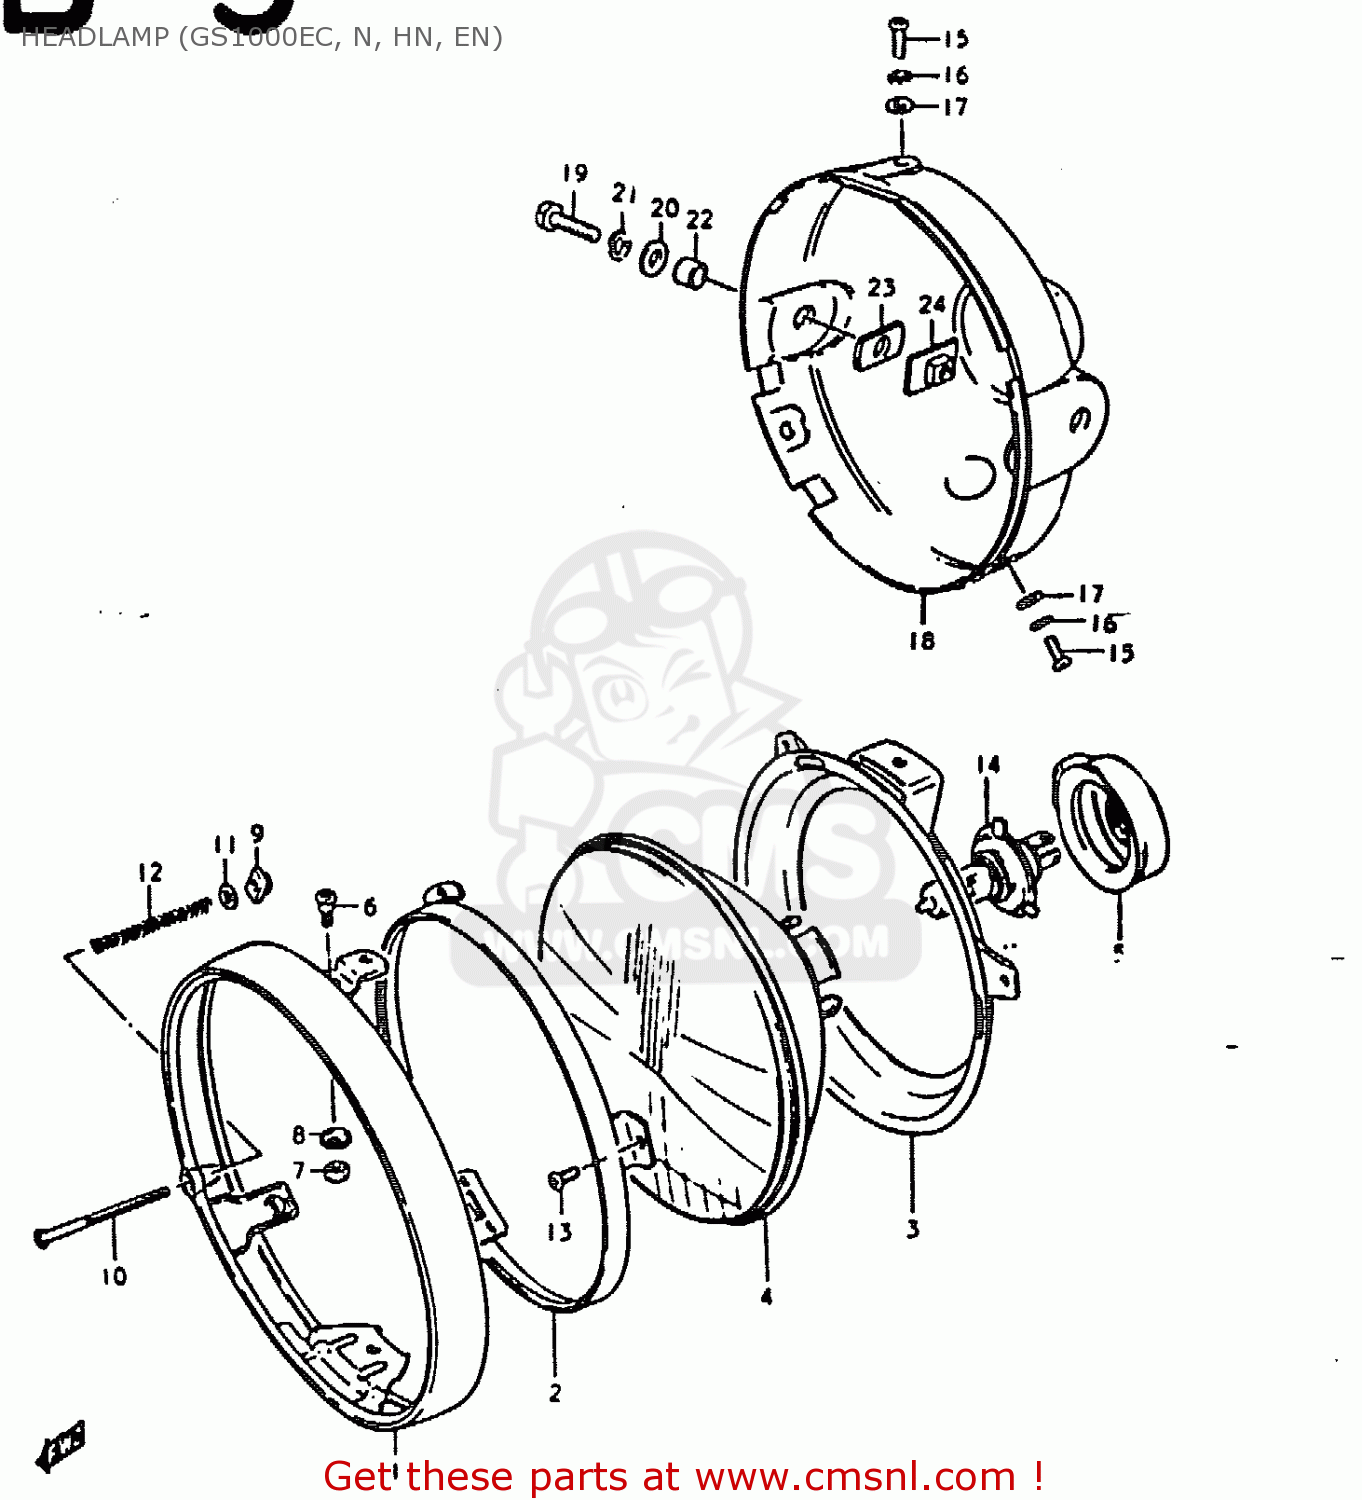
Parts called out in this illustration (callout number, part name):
1	RIM
2	RETAINER
3	RING,HEADLAMP UNIT
4	LAMP UNIT
5	COVER,HEADLAMP SOCKET
6	SCREW
7	NUT,ADJUSTING
8	SPACER
9	NUT
10	SCREW,HEADLAMP ADJUST
11	WASHER
12	SPRING,HEADLAMP ADJUST
13	SCREW
14	BULB(12V60/55W,H4)
15	SCREW
16	WASHER,LOCK
17	WASHER
18	HOUSING,HEADLAMP(BLACK)
19	BOLT
20	WASHER
21	LOCK WASHER
22	SPACER (8.8X12X7)
23	CUSHION
24	PLATE,HEADLAMP HOUSING
